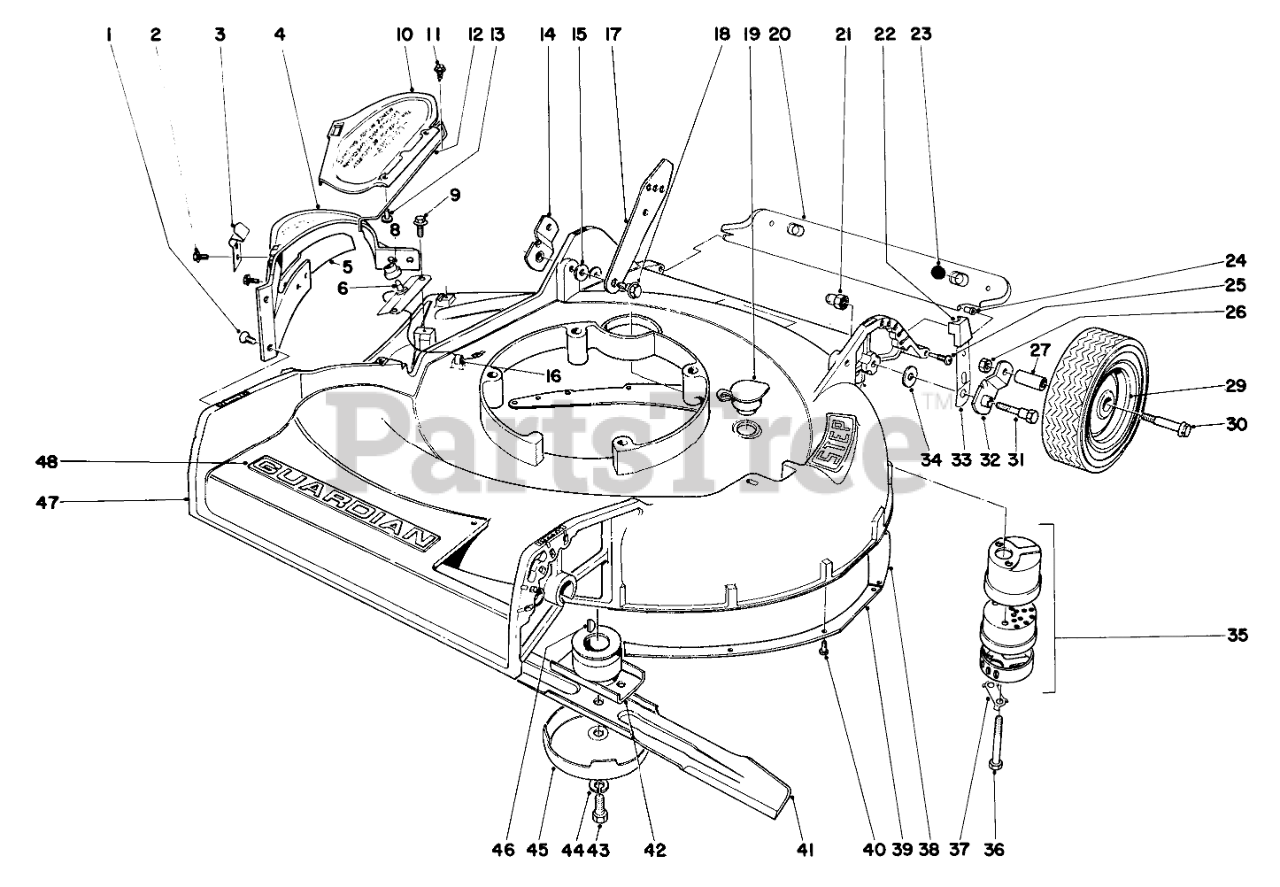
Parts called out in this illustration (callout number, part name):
1	Screw
3	Latch
4	Deflector (Incl. Ref. Nos. 2-5)
5	DefIector Bar
6	Deflector Switch & Wire (Incl. Ref. No. 8)
8	Boot Switch
10	Deflector (Incl. Ref. Nos. 12 & 13)
11	SCREW
12	Hinge Pin
13	Rivet
14	Pivot Arm
15	SPACER
17	Handle Latch
18	SCREW-SHOULDER
19	WASHOUT PLUG
20	Safety Shield (Incl. Ref. Nos. 23 & 24)
21	HANDLE PIVOT NUT
22	Knob
23	SKID BUTTON
24	SAFTEY SHIELD BUSHING
25	SAFTEY SHIELD SCREW
26	Nut
27	Bushing
29	Wheel Assembly (Incl. Ref. No. 27)
31	5/16-18 PIVOT SCREW
32	Pivot Arm
33	Spring Arm
34	WASHER-PIVOT
35	Muffler (Incl. Ref. Nos. 36 & 37)
36	SCREW-HH
37	CLIP - LOCKING
38	Main Skirt
39	Secondary Skirt
41	Blade
42	BLADE RETAINER WA
43	SPECIAL SCREW
44	WASHER-LOCK
45	AntiScalp Cup
46	KEY-WOODRUFF
47	Housing (Incl. Ref. Nos. 38, 39 & 40)
48	Emblem
